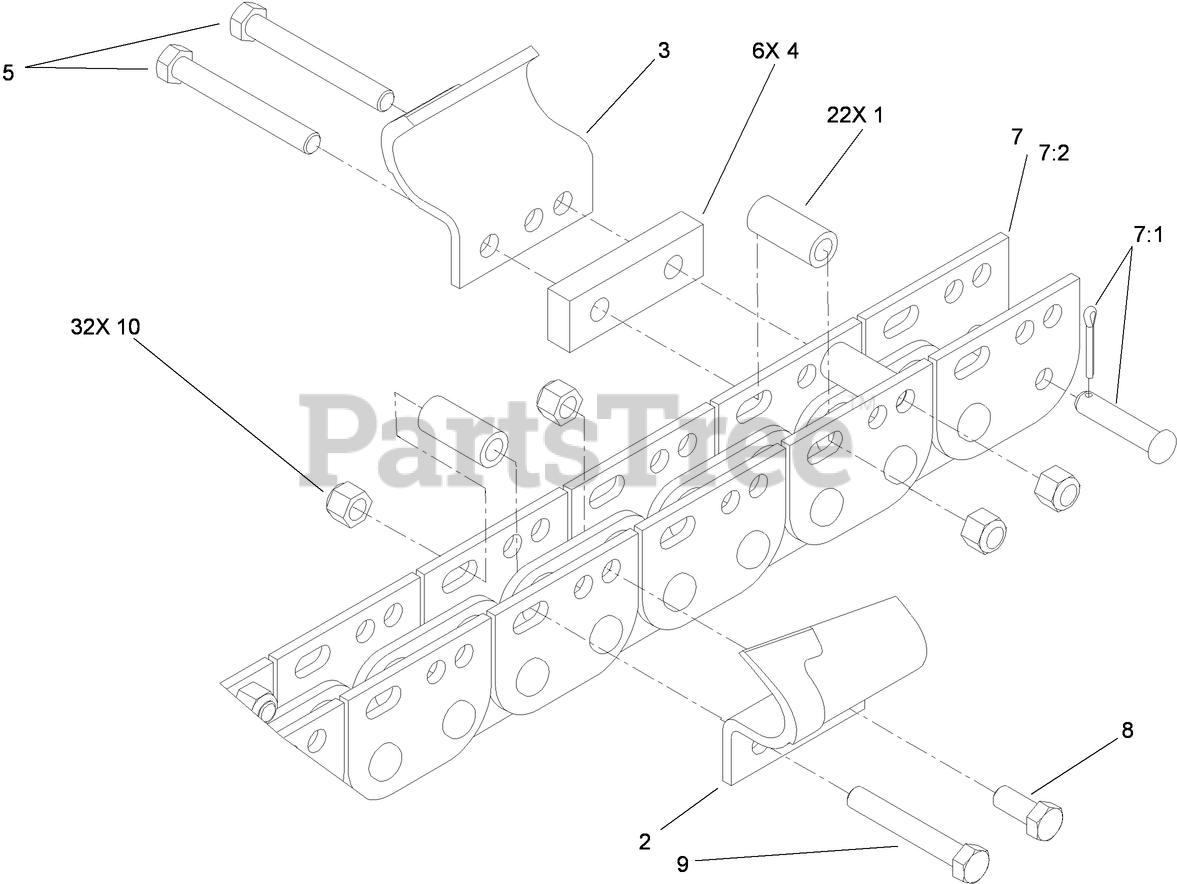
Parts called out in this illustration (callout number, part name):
1	SPACER-TUBE
2	TOOTH-SOIL, LH
3	TOOTH-SOIL, RH
4	SPACER-CUT, 5 INCH
5	SCREW-HH
7	CHAIN-BARE, 32 STATION
7:1	PIN-CONNECTING,
7:2	KIT-REPAIR, LINK
8	SCREW-HH
9	SCREW-HH
10	NUT-LOCK
